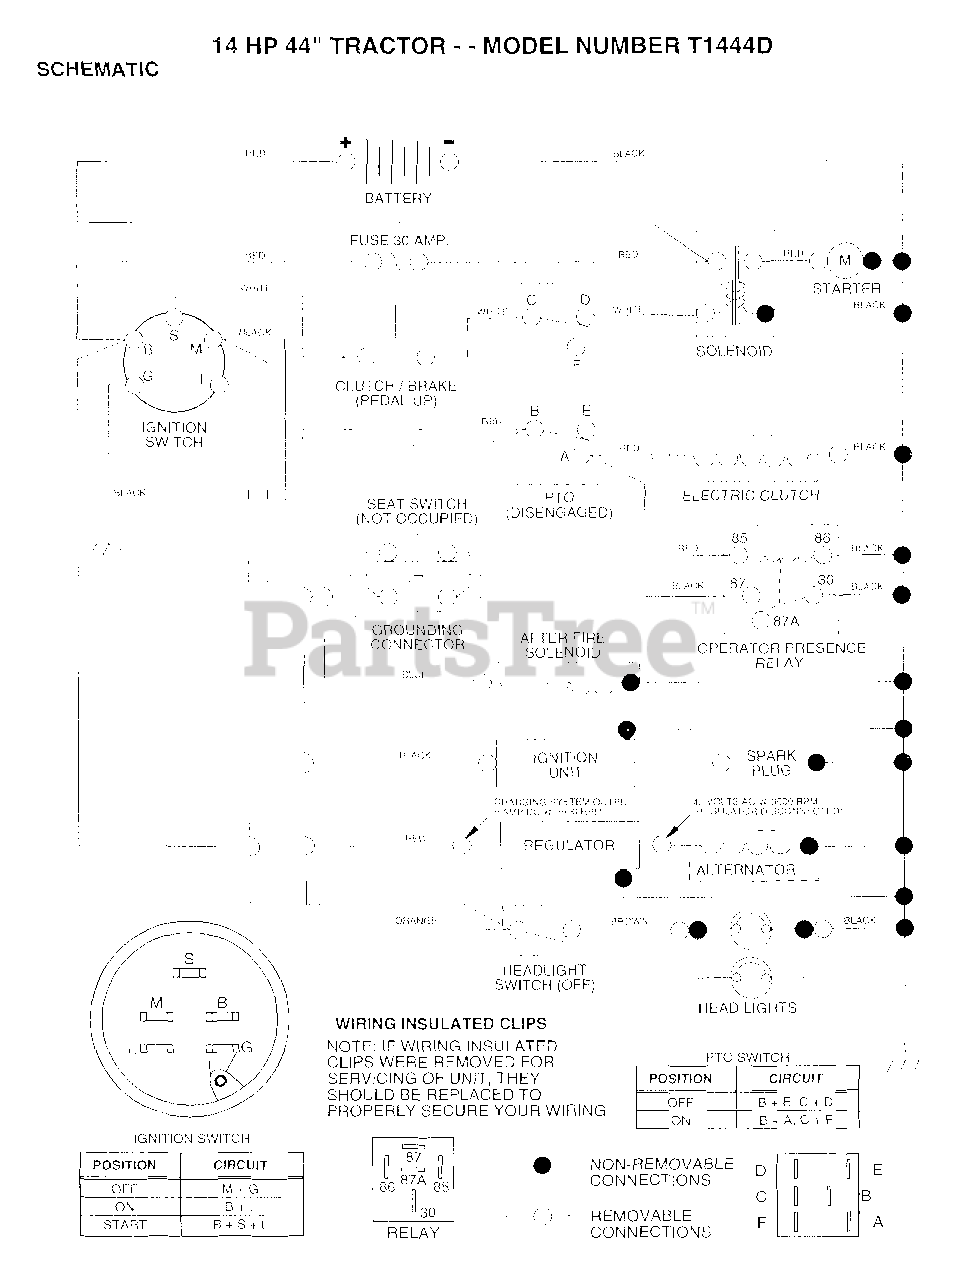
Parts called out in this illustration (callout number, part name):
1	KEY
2	"HARNESS,LIGHT SOC"
3	HEADLAMP BULB
6	NUT IGNITION
7	SWITCH LT
10	NUT
11	BOLT
13	NUT
15	HARNESS.IGN
16	CABLE T
18	"CABLE T, BATTERY"
19	HOSE CLAMP T
21	TUBE T
22	SWITCH-INTER. GT
23	SCREW
24	FUSE HYT
25	BOLT LT
26	WASHER
27	LOCKWASHER
29	BRACKET LT
34	"SWITCH,PTO"
35	HEX NUT T
37	RELAY ASSY T
39	LOCKWASHER
45	SWITCH SEAT
48	"CAP,BATTERY "
49	WASHER
